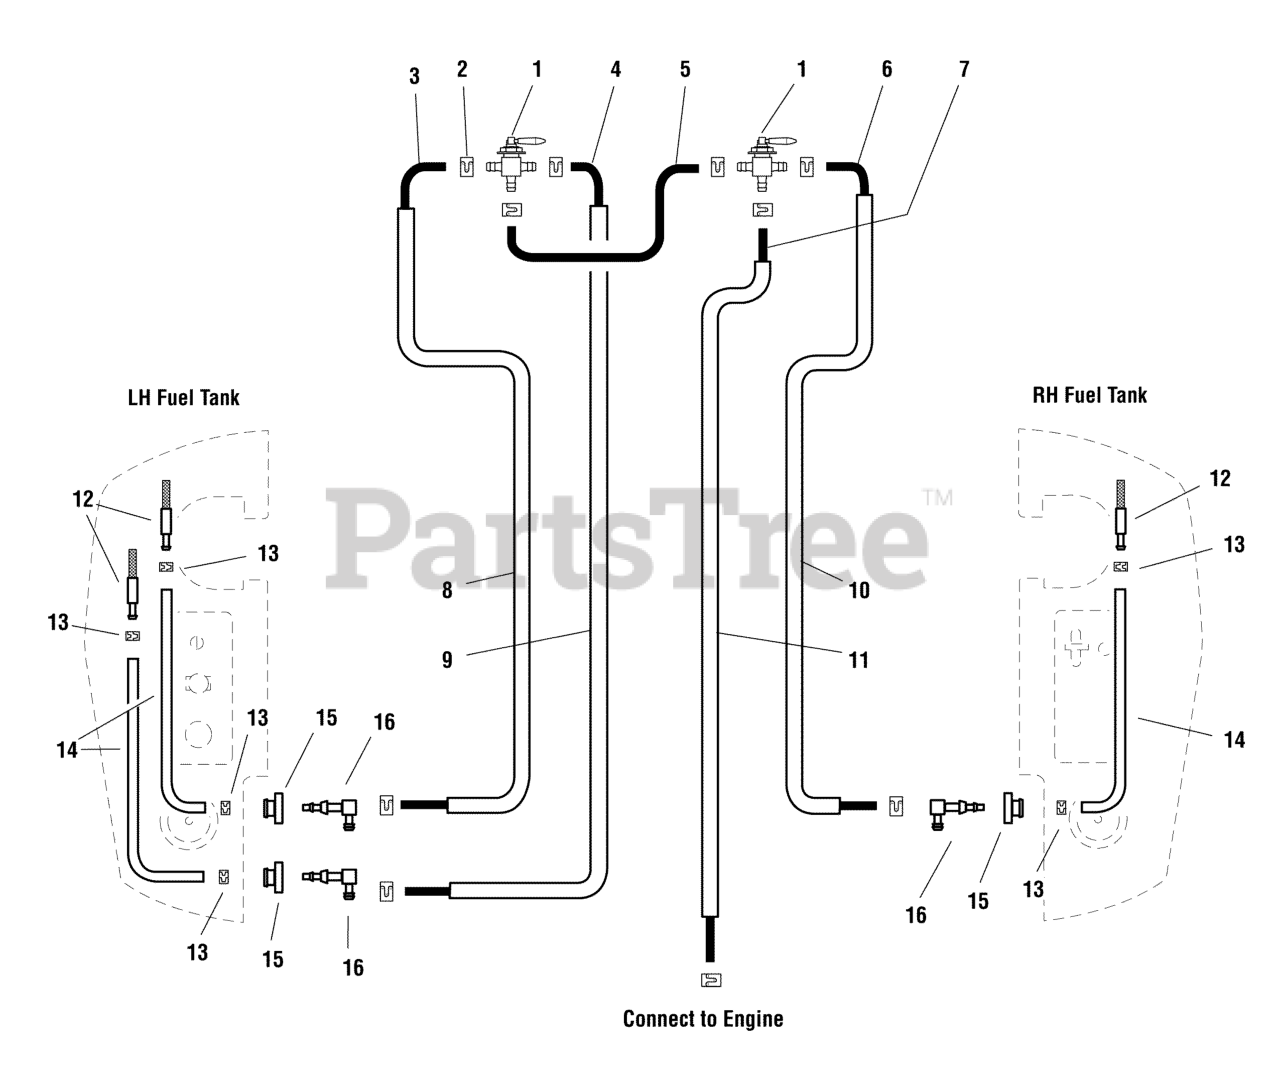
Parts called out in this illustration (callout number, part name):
1	VALVE, Fuel Shut Off
2	CLAMP, Hose
3	1/4" Fuel Line, 54" Long
4	1/4" Fuel Line, 56" Long
5	1/4" Fuel Line, 7-1/2" Long
6	1/4" Fuel Line, 45" Long
7	1/4" Fuel Line, 51" Long
8	WIRE LOOM, 53"
9	WIRE LOOM, 55"
10	WIRE LOOM, 44"
11	WIRE LOOM, 50"
12	SEE HOSE ASSEMBLY
13	SEE HOSE ASSEMBLY
14	ASSM, FUEL HOSE, 20"
15	BUSHING-FUEL TANK RED RUBBER
16	ELBOW FITTING
